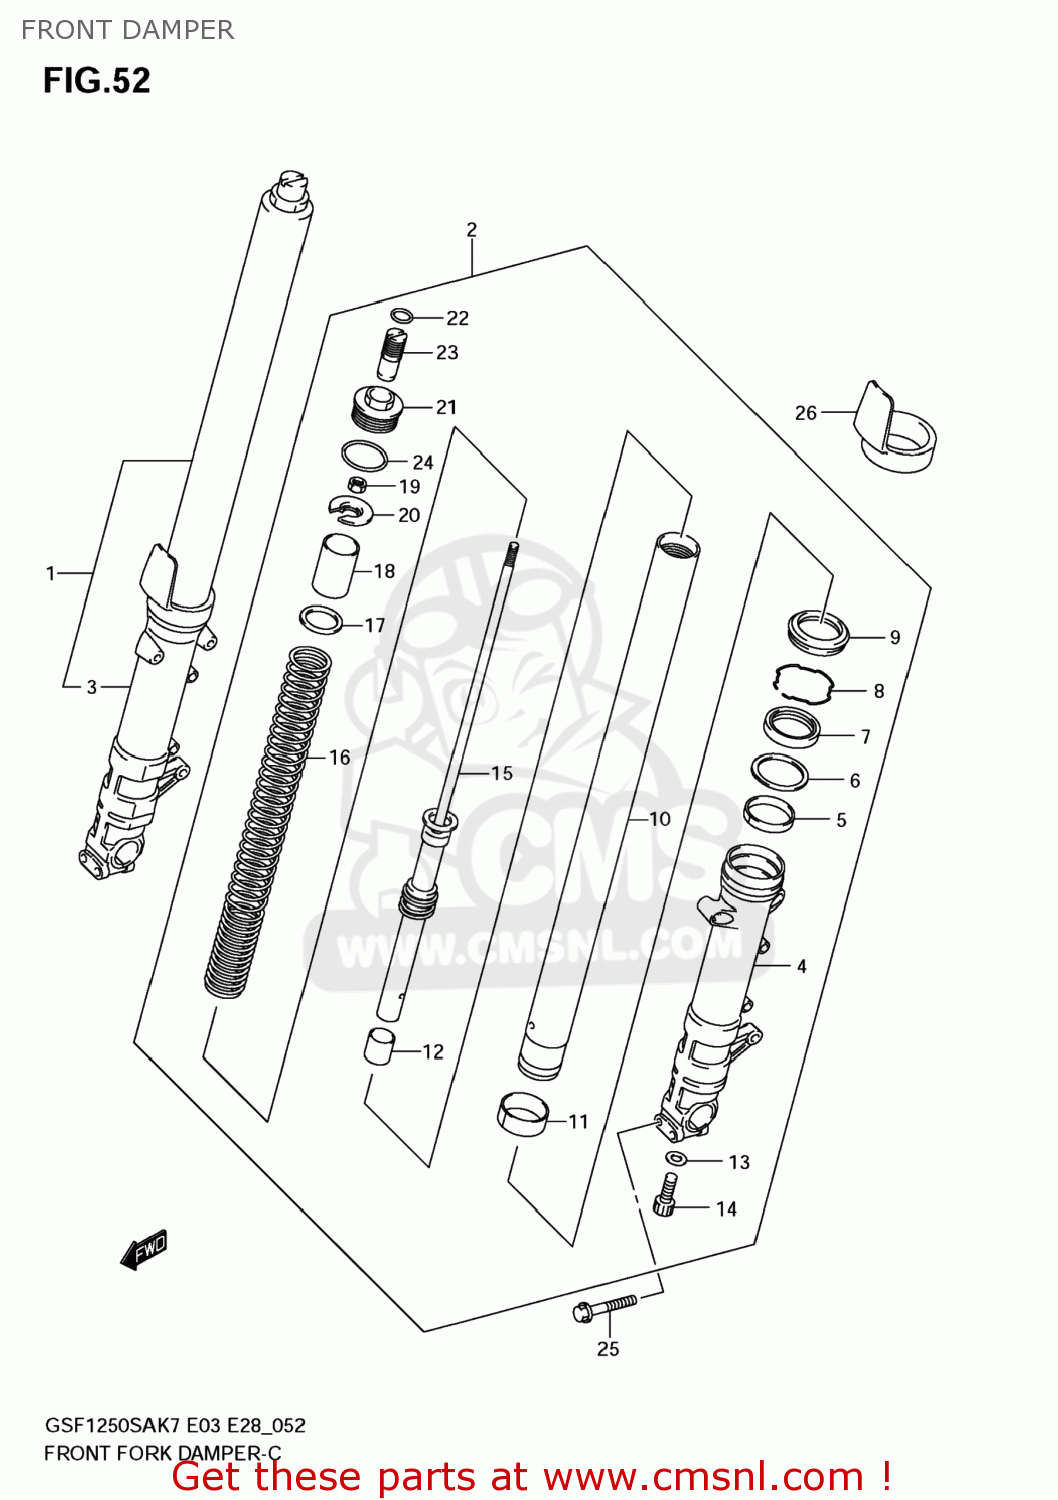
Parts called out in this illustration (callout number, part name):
1	DAMPER ASSY,FR FORK,R(BLACK)
2	DAMPER ASSY,FR FORK,L(BLACK)
3	TUBE,OUTER,R(BLACK)
4	TUBE,OUTER,L(BLACK)
5	BUSH,GUIDE
6	SPACER,SEAL
7	SEAL,OIL
8	CIRCLIP,FORK OIL SEAL
9	SEAL,DUST
10	TUBE,INNER
11	BUSH,SLIDE
12	PIECE,OIL LOCK
13	GASKET (NAS)
14	BOLT(8X27)
15	ROD,FR DAMPER
16	SPRING,FR
17	SEAT,SPRING LWR
18	COLLAR,SPRING(32.9X34X50)
19	NUT
20	SEAT,SPRING UPR
21	BOLT,FORK
22	O RING(D:2.5,ID:13.8)
23	ADJUSTER,SPRING
24	O RING
25	BOLT(8X45)
26	PROTECTOR
